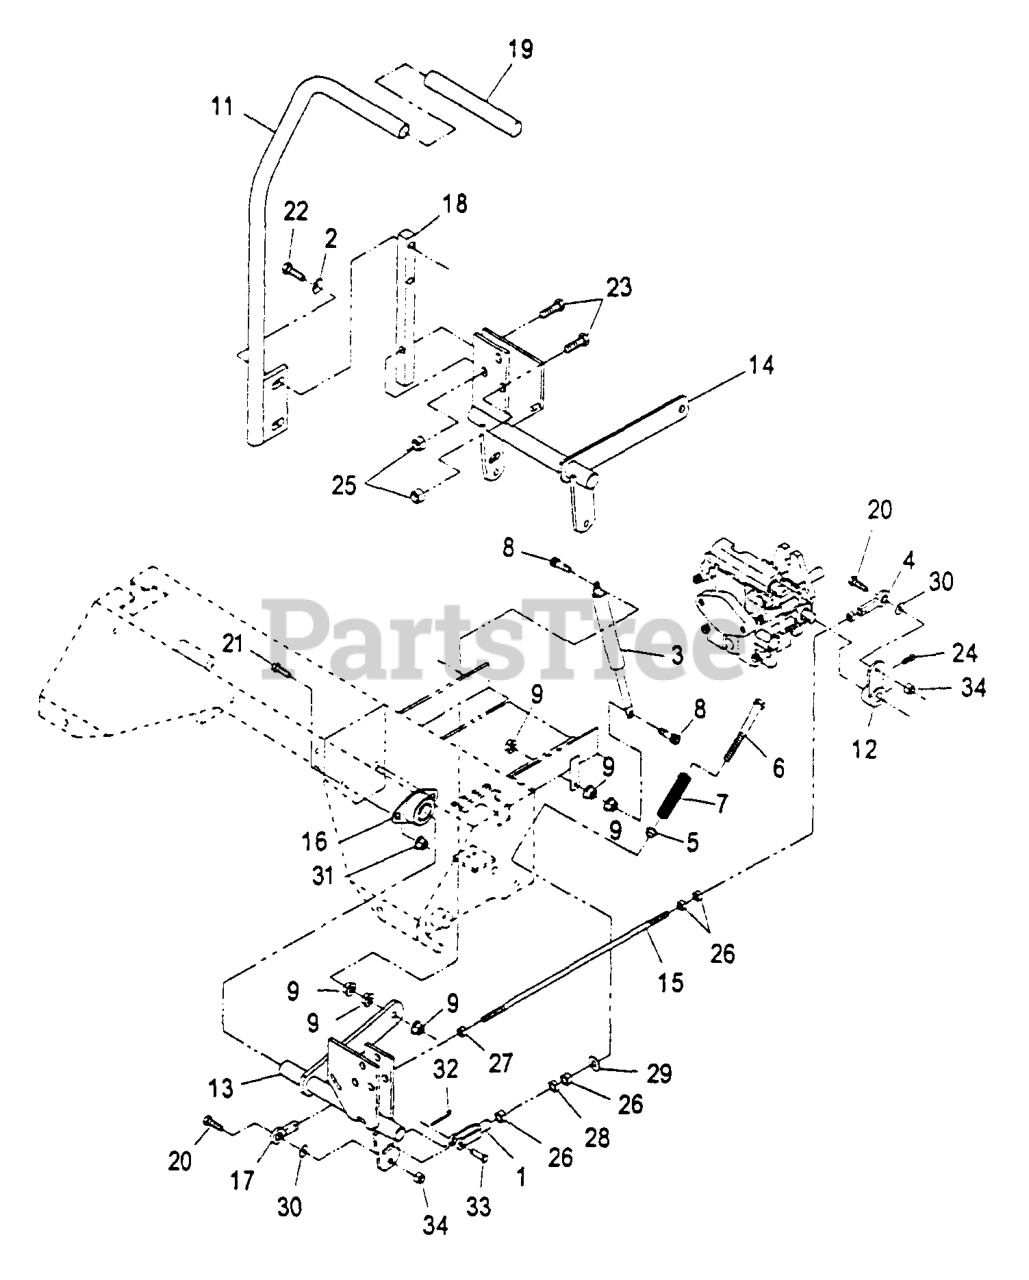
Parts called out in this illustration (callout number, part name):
1	YOKE-ADJUSTABLE
4	BALLJOINT-RH
5	BUSHING-FLANGED
6	BOLT-RETURN, NEUTRAL
7	SPRING-RETURN, NEUTRAL
8	SCREW-HH
11	ASM,LEVER/GRIP RH
14	CONTROL-MOTION, RH
16	BEARING-FLANGE, SIDE
17	BALLJOINT-LH
18	ARM-CONTROL, SHAFT
19	GRIP-CONTROL, MOTION
24	SCREW-SET
33	PIN-CLEVIS
